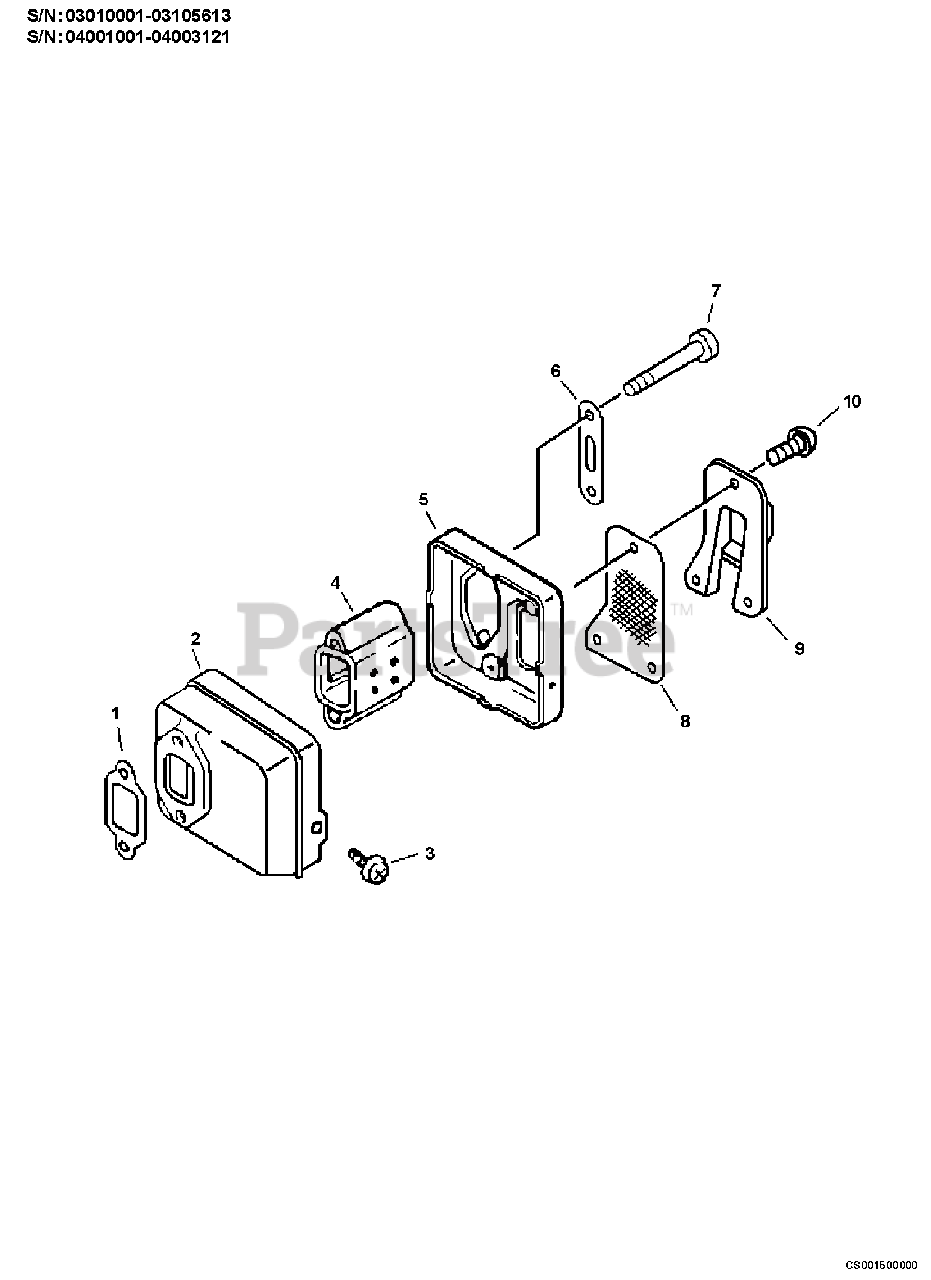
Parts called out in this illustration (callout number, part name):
1	GASKET, MUFFLER
3	SCREW TAPPING 4×8
4	SILENCER
5	COVER, MUFFLER
6	PLATE, EYE
7	BOLT 6 MM
8	SCREEN, SPARK ARRESTER
9	COVER, MUFFLER
10	SCREW TAPPING 4×8
